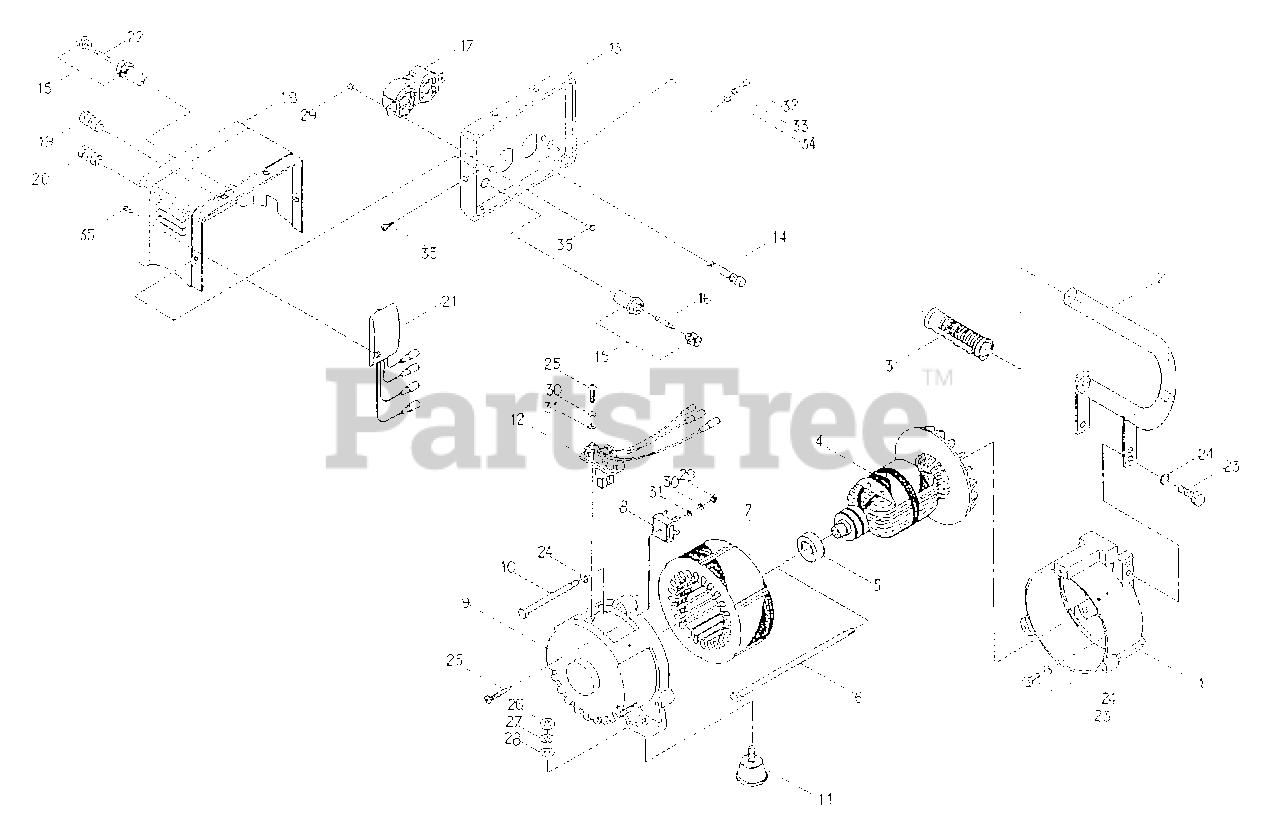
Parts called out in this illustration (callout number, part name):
1	BRACKET - FRONT
2	HANDLE
3	GRIP
4	ROTOR ASSY
5	BEARING, BALL
6	THRU BOLT
7	STATOR ASSY
8	BLOCK, DIODE
9	BRACKET - REAR
10	BOLT, BRACKET
11	RUBBER MOUNT UNIT
12	BRUSH HOLDER ASSY
13	PANEL A
14	NEON LAMP - 110V
15	HOLDER, FUSE
16	FUSE
17	OUTLET - 125V 15A
18	CONTROL BOX ASSY
19	OUTPUT TERMINAL - BLACK
20	OUTPUT TERMINAL - RED
21	AVR UNIT
22	FUSE
23	BOLT - 6X15
24	LOCKWASHER - 6
25	SCREW - 4X25
26	NUT - 8
27	LOCKWASHER - 8
28	WASHER - 8
29	NUT - 4
30	LOCKWASHER - 4
31	WASHER - 4
32	BOLT - 5X15
33	LOCKWASHER - 5
34	WASHER - 5
35	SCREW - 4X10 -- TAPPING
